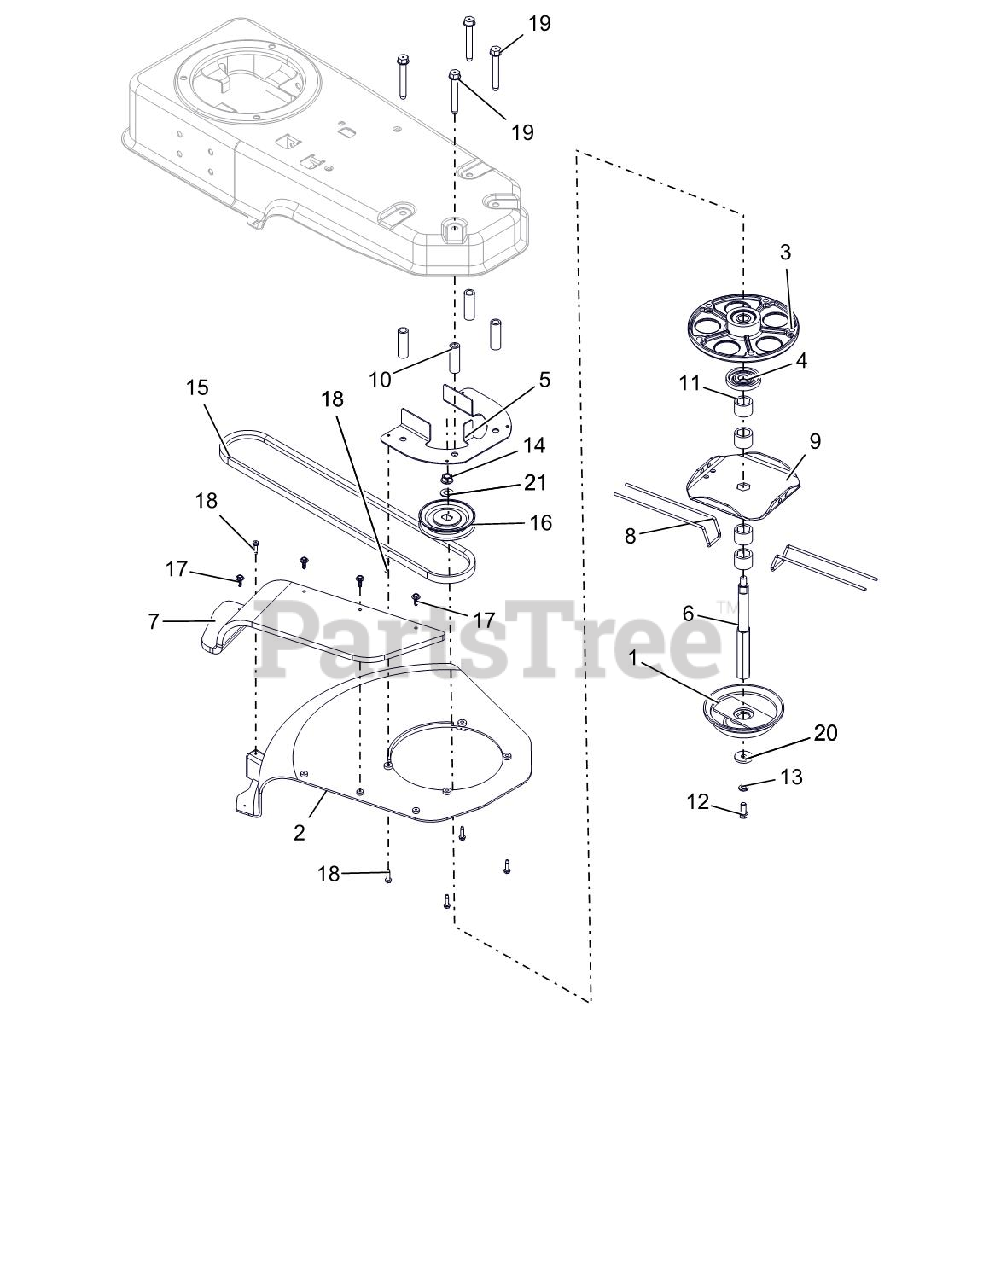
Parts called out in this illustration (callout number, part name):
1	WELDMENT, HEIGHT GUIDE
2	SHIELD - TRIMMER
3	HOUSING - JACKSHAFT
4	SHIELD - DUST
5	FINGER - BELT
6	SHAFT - CUTTER - HEX
7	GUARD - DEBRIS
8	LINE - CUTTER 18" LG PKG OF 6
9	CUTTER - DISK
10	BSHG-SPCR .406X.625X1.90
11	SPACER - HEX
12	@BLT-HEX .31-18X.75 GR5 YWZC
13	@WSHR-LK .31X.078 REG YWZC
14	NUT-LK-FLG .375-24 GR5 YWZC
15	V-BELT, HA-RAW EDGE
16	PLY-V 3.50 OD X .87 WIDE (CUT)
17	SCR-TAP #10-16 X .625 HWH
18	SCR-TAP 10-24X.75 HWH TR YWZC
19	@SCR-TAP.375-16X2.75 HWH TR YZ
20	WSHR-FL-STL .344X1.125X.135
21	@WSHR-FL-STL.406X.812X.065 YWZ
